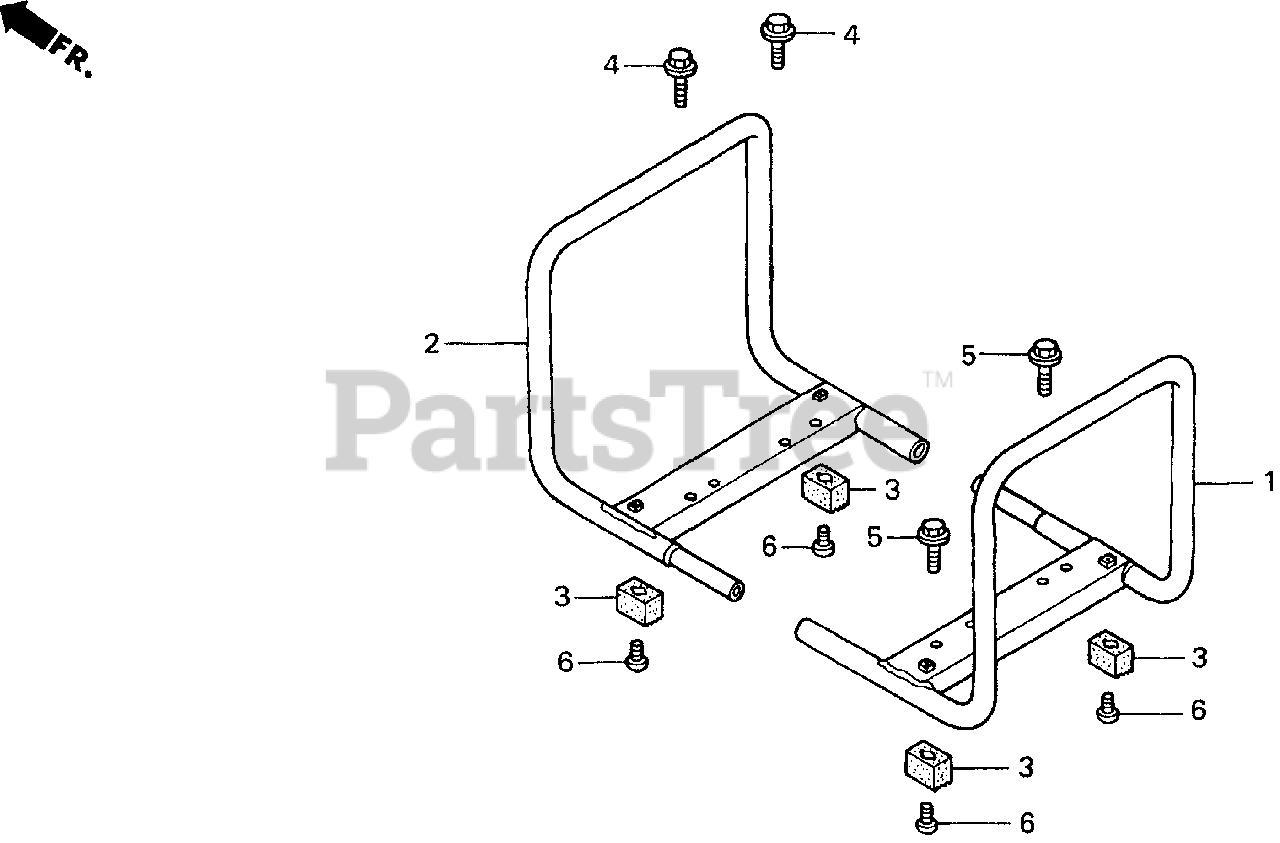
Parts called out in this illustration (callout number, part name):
1	FRAME, PUMP
2	FRAME, ENGINE
3	RUBBER (LOWER)
4	BOLT, FLANGE (8X28)
5	BOLT, FLANGE (8X25)
6	SCREW, PAN (6X10)
